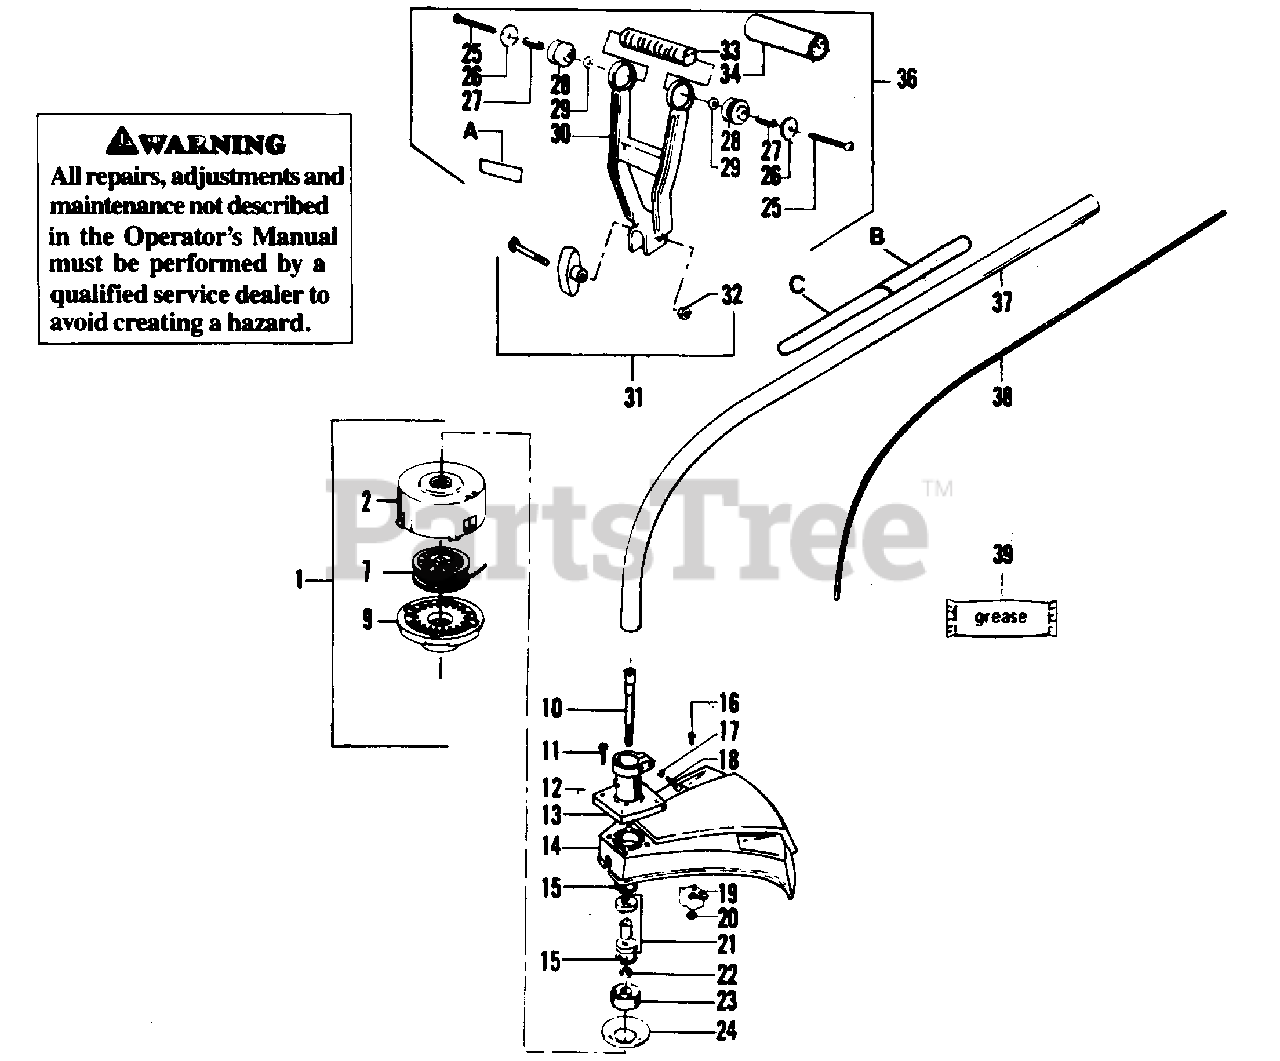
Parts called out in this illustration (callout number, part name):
1	Trimmer Head Ass'y.
2	Hub w/Line Saver
7	Spool w/Line
8	Tap Button
10	Arbor Shaft
11	Screw-1/4-10 x 1-1/8"-Shield to Bearing Housing
12	Screw-#10-16 x 14"-Self Tapping
13	Bearing Housing Ass'y.
14	Shield Assembly-18"
15	Retainer-Bearing
16	Screw-#10-24 x 5/8"-Hex Hd. Line Limiter
17	Washer-1/4" Int. Tooth Lock
18	Screw-Pinch Clamp-#14-20 x 1"
19	Line Limiter Assembly
20	Nut-#10-24-Locking
21	Bearings & Spacer Kit
22	Washer-3/8"-Dust Cup
23	Dust Cup
24	Grass Washer
25	Screw-Pan Hd.-#12-11 x 2"
26	Cup-Isolator
27	Spacer Isolator
28	Isolator-Handle
29	Washer-1/4 Flat
30	Handle-Anti-Vibe
31	"T" Handle Kit
33	Center Section-Handle
34	Cushion-Handle Center Section
35	Screw-1/4-20 x 1-5/8"
36	Handle-Anti-vibe Assembly
37	Drive Shaft Housing
38	Flexible Drive Shaft
39	Flex Shaft Lube
A	Decal-Anti-Vibe
B	Decal-Safety Label (Upper)
C	Decal-Safety Label (Lower)
